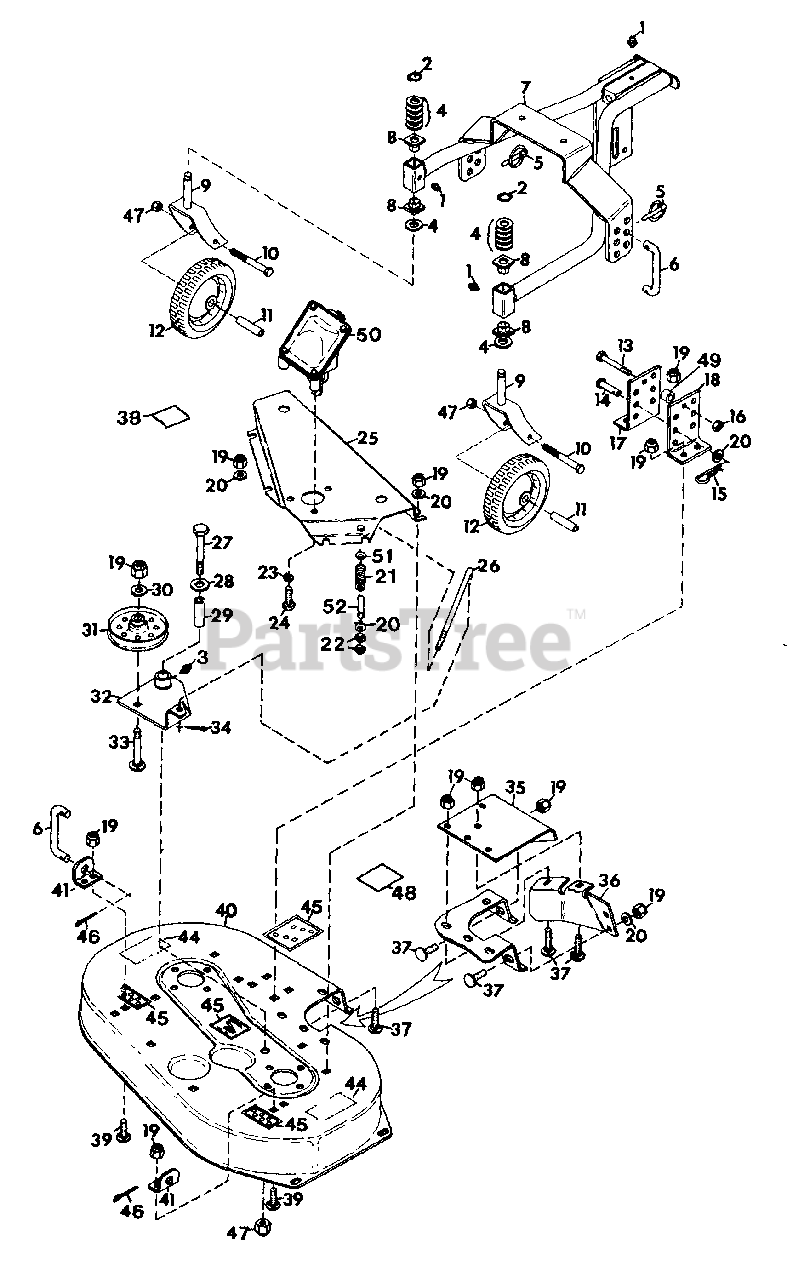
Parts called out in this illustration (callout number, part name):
1	Fitting-Lube .25-28 x .256
2	Ring-Retaining-Internal .750 x .042
3	Fitting-Lube .25-28 x .46
4	Washer-Flat-Steel .813 x 1.370 x .100
5	Pin-Klik 1.000 x .188 x 1.25
6	Rod, Adjusting
7	Weldment, Support
8	Bushing-Flange .610 x 1.200 x 1.04 x .190
9	Weldment, Caster
10	Bolt-Hex .50-13 x 5.00
11	Spacer .532 x .748 x 3.34
12	Wheel Hub 3.25 x .75
13	Bolt-Hex .25-20 x 1.25 Grade 5
14	Pin, Clevis .375 x .948
15	Pin-Cotter .05 x 1.157
16	Nut-Locking-Nylon .250-20 Grade 2
17	Bracket, Rear Support
18	Bracket, Rear Support
19	Nut-Locking-Nylon .375-16 Grade 2
20	Washer-Flat-Steel .406 x .812 x .065
21	Spring-Compression .125 x .78 x 1.00
22	Nut-Hex .375-24
23	Washer-Lock .50 Reg.
24	Bolt-Hex .50-13 x 1 Grade 5
25	Guard, Belt
26	Rod, Idler 40 inch Mower
27	Bolt-Hex .50-13 x 2.00 Grade 5
28	Washer-Flat-Steel .531 x 1.062 x .095
29	Spacer .516 x .874 x .998
30	Washer-Flat-Steel .438 x 1.000 x .083
31	Pulley-Idler 4.50 x .380
32	Weldment, Idler Pivot
33	Bolt-Round Head Square Neck .38-16 x 2.00
34	Pin-Cotter .06 x 1.00
35	Shield, Discharge
36	Shroud, Blade
37	Bolt-Round Head Square Neck .38-16 x 1.0
38	Decal, Warning Eye
39	Bolt-Round Head Square Neck .375-16 x .75 Grade 1
40	Deck, 40 Inch Mower
41	Bracket, Mower Support
44	Decal, Danger Foot
45	Decal, 40" Com Mower
46	Pin-Cotter .12 x .75
47	Nut-Locking-Nylon .50-13 Grade 5
48	Decal, Danger Hand
49	Spacer .277 x .375 x .440
50	Assembly-Gearbox
51	Washer
52	Sleeve, Rod
